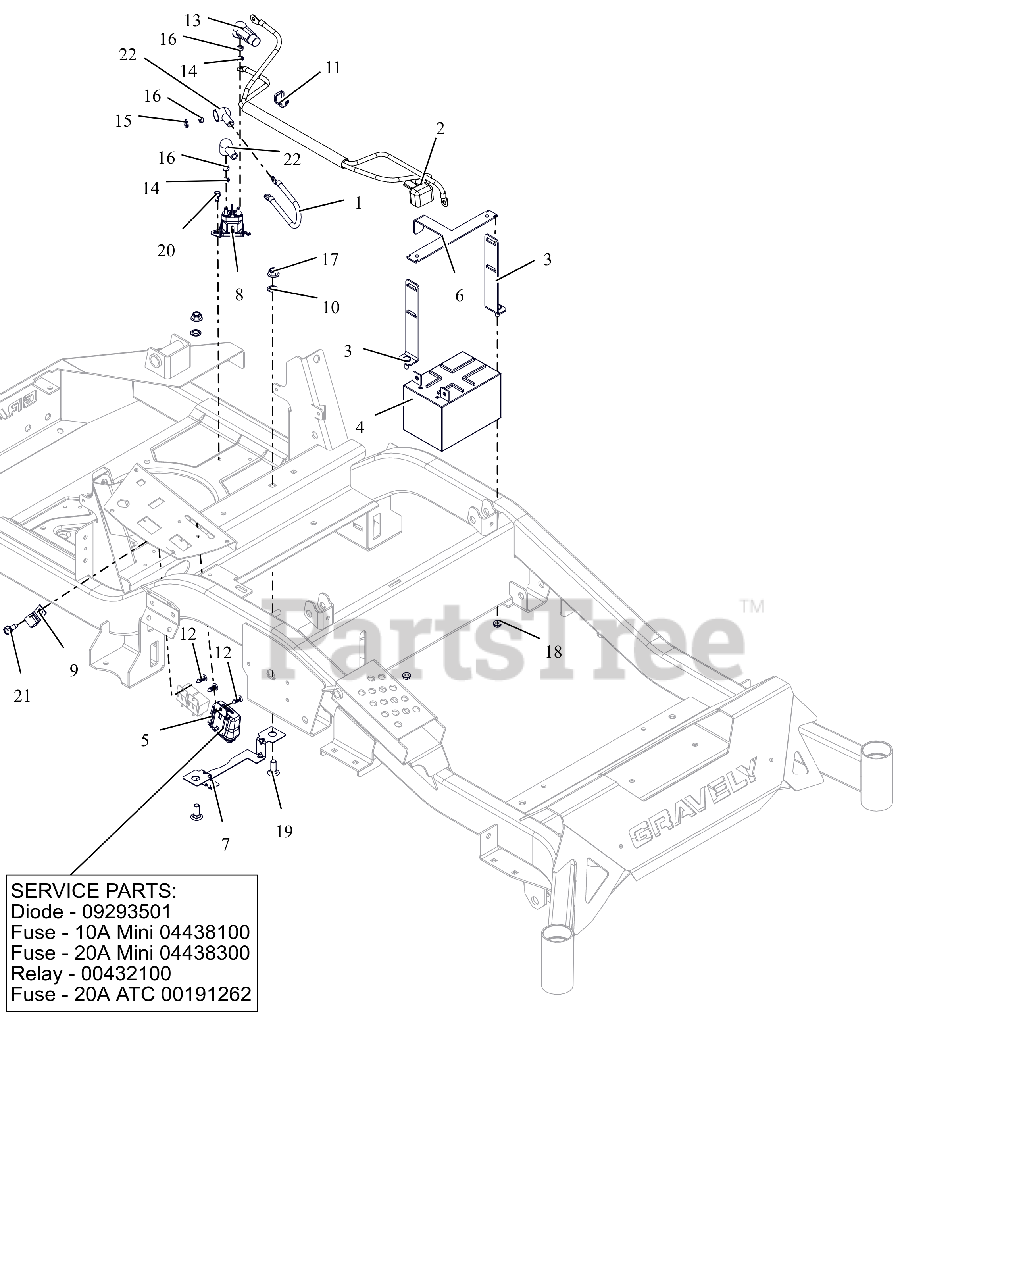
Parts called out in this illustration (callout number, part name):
1	CABLE, POS W/(2)1/4 RING 9.0LG
2	HARNESS, BATTERY HD
3	WMT,BATTERY MOUNT HOLD DOWN
4	BATTERY, 12V 12A-190CCA
5	HARNESS, WIRE
5	DIODE, CONNECTOR SHELL
5	FUSE,10 AMP MINI-ATC
5	FUSE,20 AMP MINI ATC
5	RELAY,SEALED W/DIODE
5	FUSE, 20 AMP BLADE S/O
6	BRKT, BATTERY TIE DOWN
7	GUARD, ELECTRICAL HARNESS
8	SOLENOID, STARTER (SEALED)
10	NUT-PUSH .38 DIA. PAL ZINC
11	CABLE TIE W/ TREE (.25 HOLE)
12	RIVET, .25 NYLON PANEL
13	BOOT, .65ID POS
14	WSHR,LK-EXT.262X.502X.026 ZCC
15	WSHR,LK-REG .312X.078 ZCC
16	NUT-STD M6-1.0 ZCC
17	NUT,NYL-FLG .38-16 GF ZCC
18	NUT-LK-TOP-FLG .250-20 GF ZCC
19	BLT, RHSN .38-16X1.00 G5 ZCC
20	SCR-TAP .25-20X.50 HWH ZCC
21	SCR,TAP .312-18X.75 HWH TR ZCC
22	BOOT, EYELET TERMINAL
